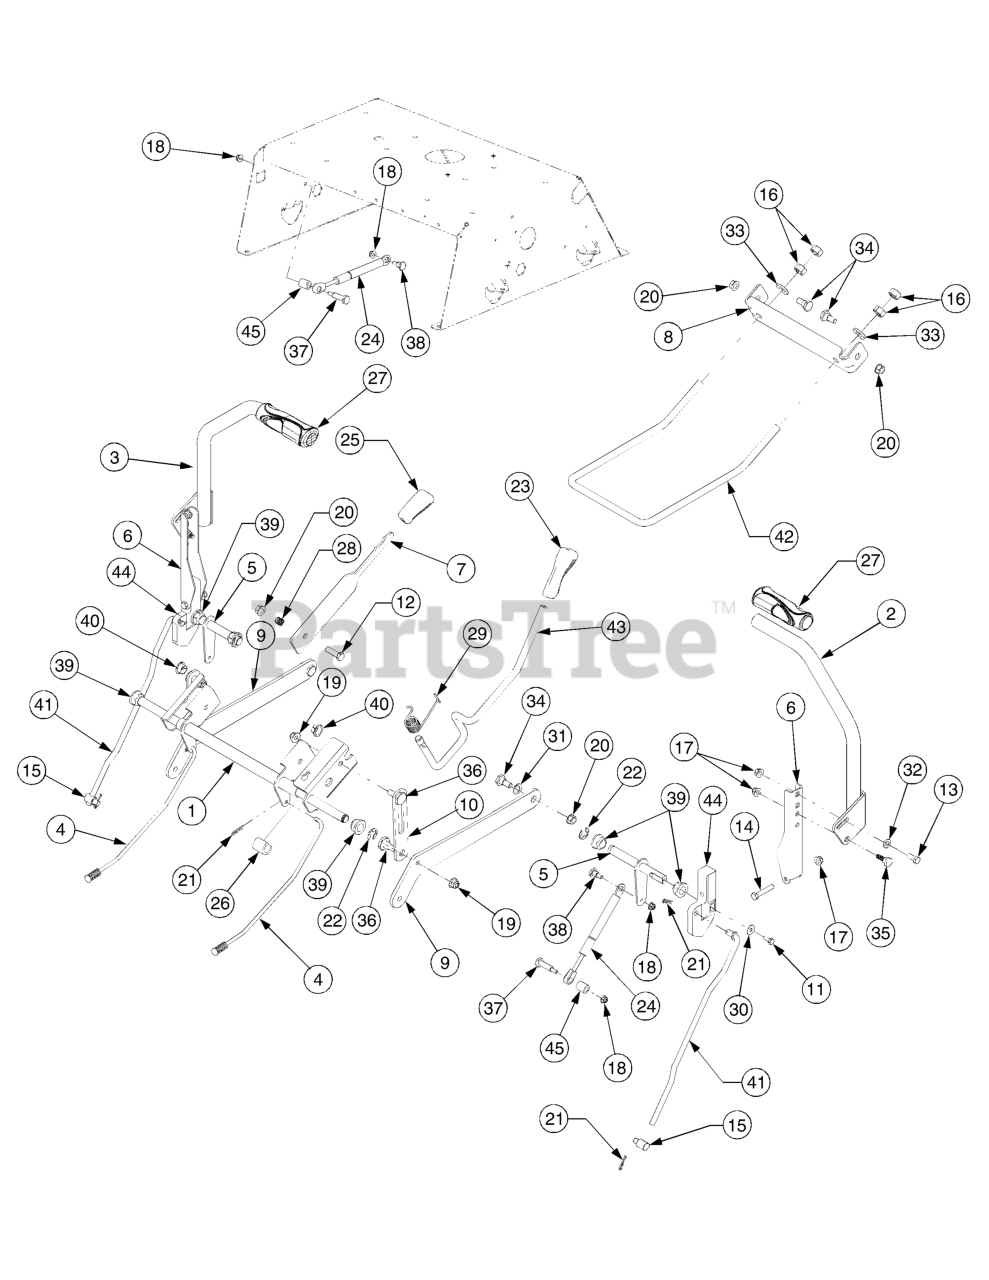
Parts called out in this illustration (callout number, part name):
4	Rod, Brake
5	Shaft, Control
6	Bracket, Lapbar Pivot
11	Screw, Hex Lock, 1/4-20 x .62 GR5
12	Screw, Hex Cap, 3/8-16 x 1.25 GR5
13	Screw, Hex Cap, 5/16-18 x .75 GR5
14	Screw, Hex Cap, 5/16-18 x 1.75 GR5
15	Ferrule, 3/8-24 x .375
16	Nut, Hex, 1/2-13 GR5
17	Nut, Hx Flange Insert Lck, 5/16-18 GrF
18	Nut, Hx Flange Insert Lck, 1/4-20 GrF
19	Nut, Hx Flange Insert Lck, 3/8-16GrF
20	Nut, Hex Flange Lock, 3/8-16 GRF
21	Pin, Internal Cotter
22	E-Ring , .625 Dia. Shaft
23	Grip, Handle
24	Cylinder, Damper
25	Grip, Handle
26	Spacer, .62 x 1.0
27	Grip, Hand
28	Spring, Compression
29	Spring, Torsion RZT
30	Washer, Bell, .265 x .75 x .062
31	Washer, Flat, .51 x 1.0 x .06
32	Washer, Flat, .344 x .688 x .065
33	Washer, Flat, .531 x 1.062 x .134 HT
34	Screw, Shoulder, .498 x .340:3/8-16
35	Screw, Shoulder, .437 x .268:5/16-18
36	Screw, Shoulder, .5 x .434:3/8-16
37	Screw, Shoulder, .374 x 1.16:1/4-20
38	Screw, Shoulder, .375 x .38:1/4-20
39	Bearing, Hex Flange
40	Bearing, Flange, .626 x .938 x .344
41	Rod, Lapbar Control
42	Rod, Deck Front Hanger
43	Rod, Deck Lift Handle
44	Hub, Control
45	Spacer, .385 x .63 x .75
